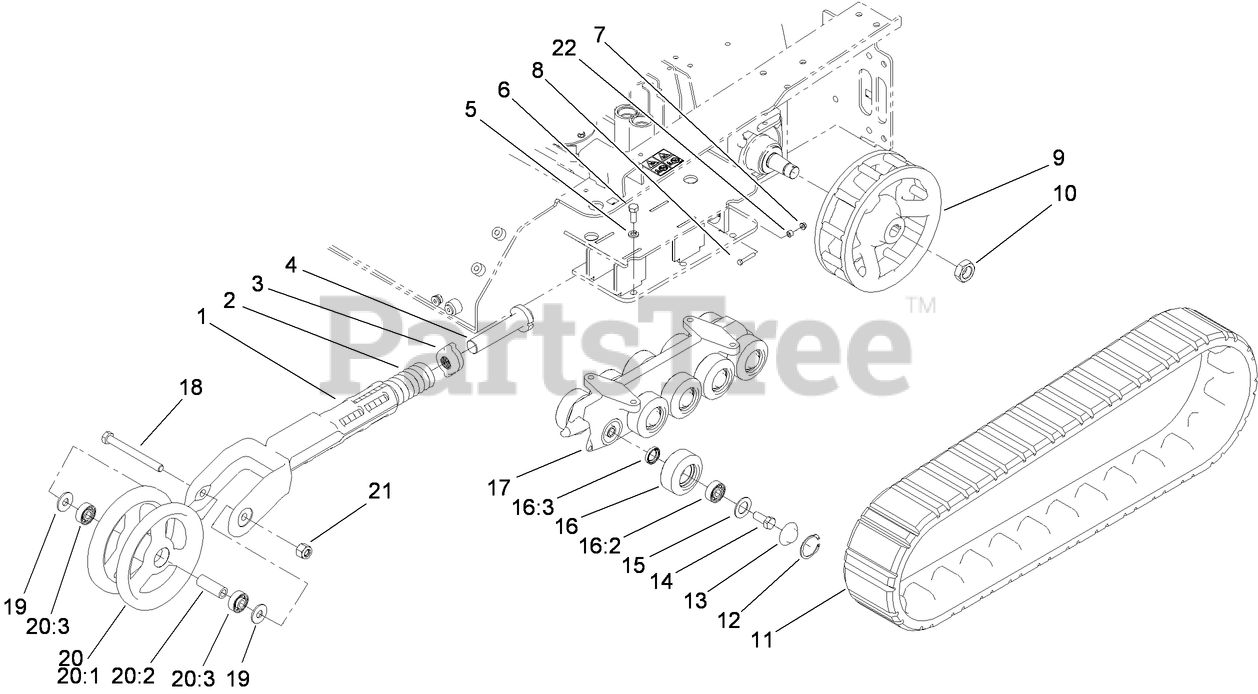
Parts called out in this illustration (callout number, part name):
1	ARM-TENSIONER
2	SPRING-COMPRESSION
3	BLOCK-TENSIONER
4	BOLT-TENSIONER
5	WASHER-LOCK
6	SCREW-HH
7	NUT-HHF
8	SCREW-HH
9	WHEEL-DRIVE
10	NUT-HEX
11	TRACK
12	RING-SNAP, INTERNAL
13	CAP-WHEEL, BEARING
14	SCREW-HH
15	Gasket-Bogie
16	Road Wheel ASM
16:2	BEARING
16:3	SEAL-OIL
17	GUIDE-TRACK
18	SCREW-HH
19	WASHER-FLAT
20	TENSIONER WHEEL ASM
20:1	WHEEL-TENSIONER
20:2	SPACER-WHEEL, TENSIONER
20:3	BEARING
21	NUT-HEX
22	SPACER
